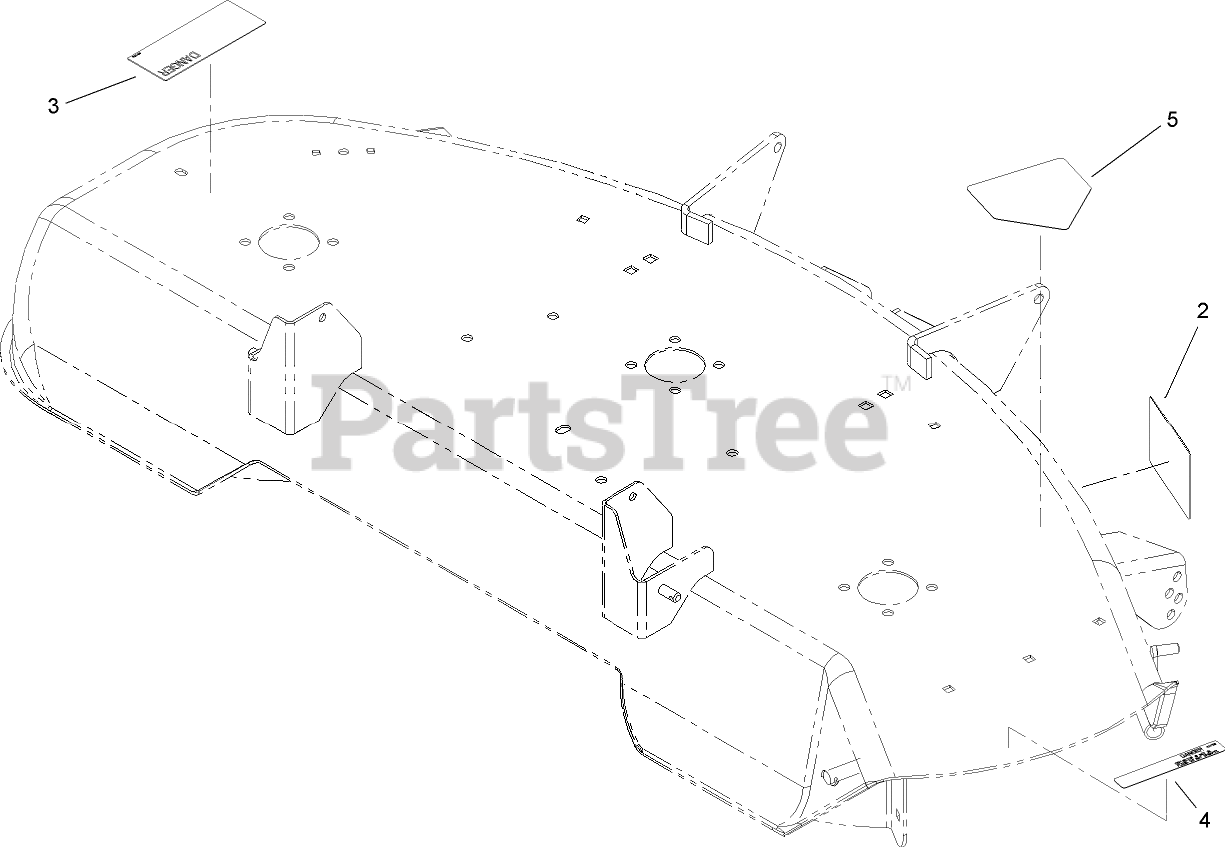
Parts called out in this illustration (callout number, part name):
2	DECAL-ANTI SCALP
3	DECAL-DANGER
4	DECAL-DANGER
5	DECAL-DANGER, SHIELD
